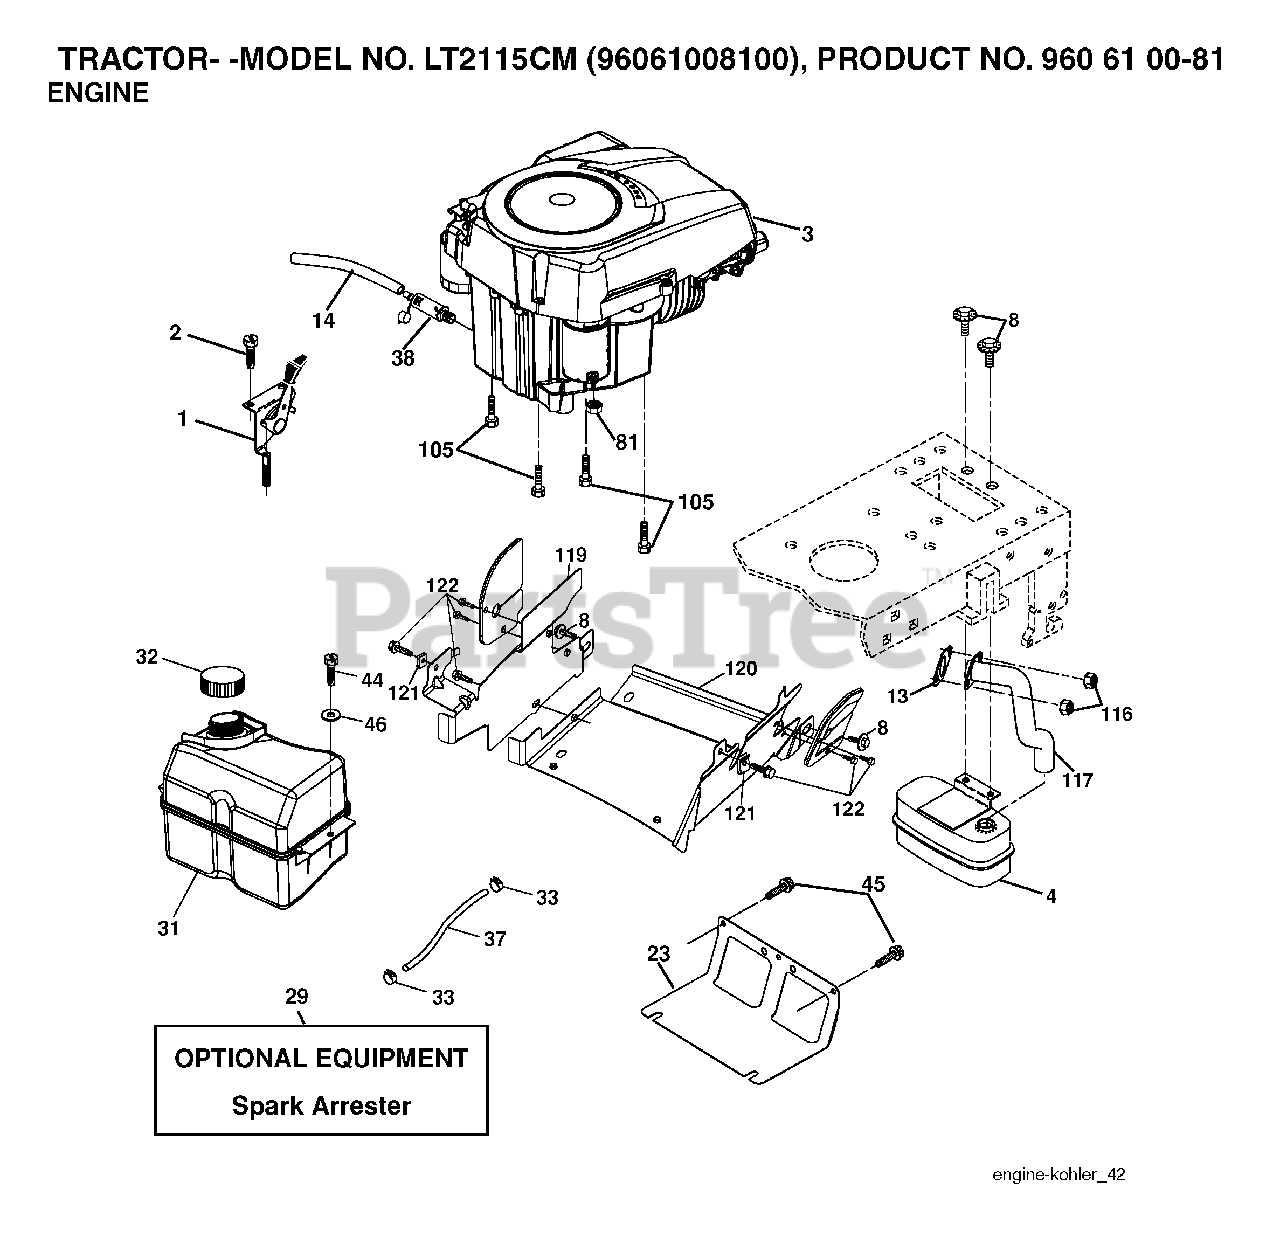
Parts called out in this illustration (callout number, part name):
1	CONTROL.THROTTLE.LT/YT
2	SCREW
4	MUFFLER.SINGLE.CYL.KOHL/B&S
8	BOLT, 5/16-18 X 1 3/4
13	GASKET ENGINE
14	TUBE, DRAIN OIL ASM.
23	SHEILD.BROWNING.DBR.GUARD
29	ARRESTER SPARK (OPTIONAL)
31	TANK FUEL
32	FUEL CAP
33	HOSE CLAMP
37	LINE.FUEL.20
38	PLUG DRAIN OIL EASY
44	SCREW HEXWSHR 1/4-20X3/4
45	SCREW, 3/8-16X3/4
81	NUT
105	SCREW 3/8-16X1
116	NUT.HEX.FLANGE.TOPLOCK
117	TUBE EXHAUST
122	SCREW.1/4-20X5/8
123	SCREW, 5/16-18 X 1/2
